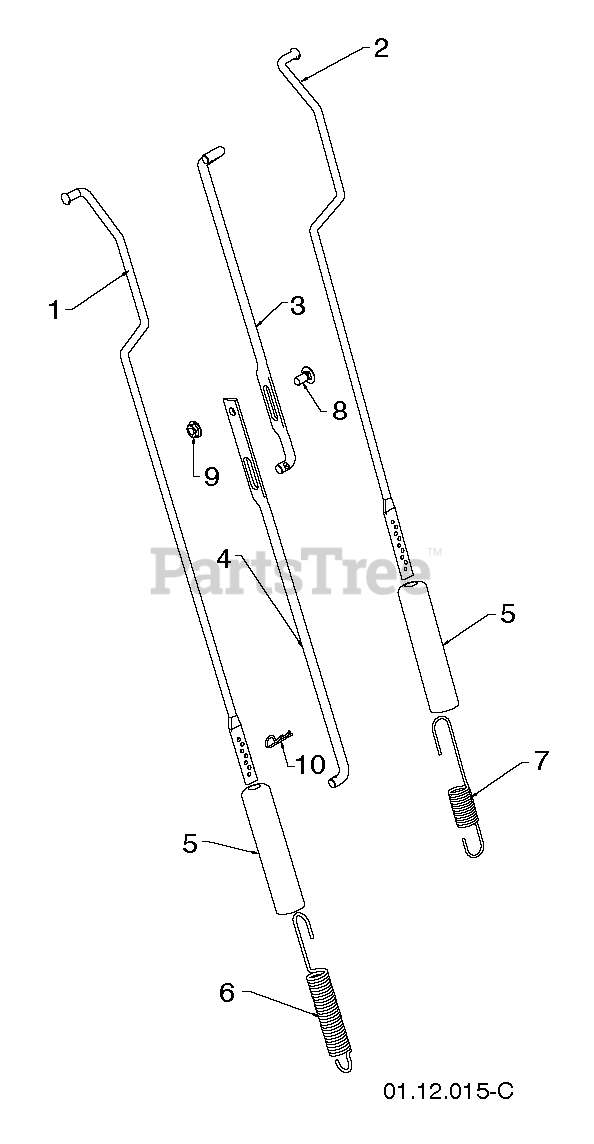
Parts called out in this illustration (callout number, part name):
1	ROD.IMPELLER.CONTROL.HYD I.13
2	ROD.TRACTION
3	ROD.SHIFTER.TOP.HYD.SNOW
4	ROD, LOWER, SPEED CONTROL
5	SLEEVE, SPRING
6	SPRING.CONTROL.ROD.SNOW
7	SPRING.TRACTION.ROD.SNOW
8	BOLT
9	NUT.FLANGE.5/16
10	SPRING RETAINER
